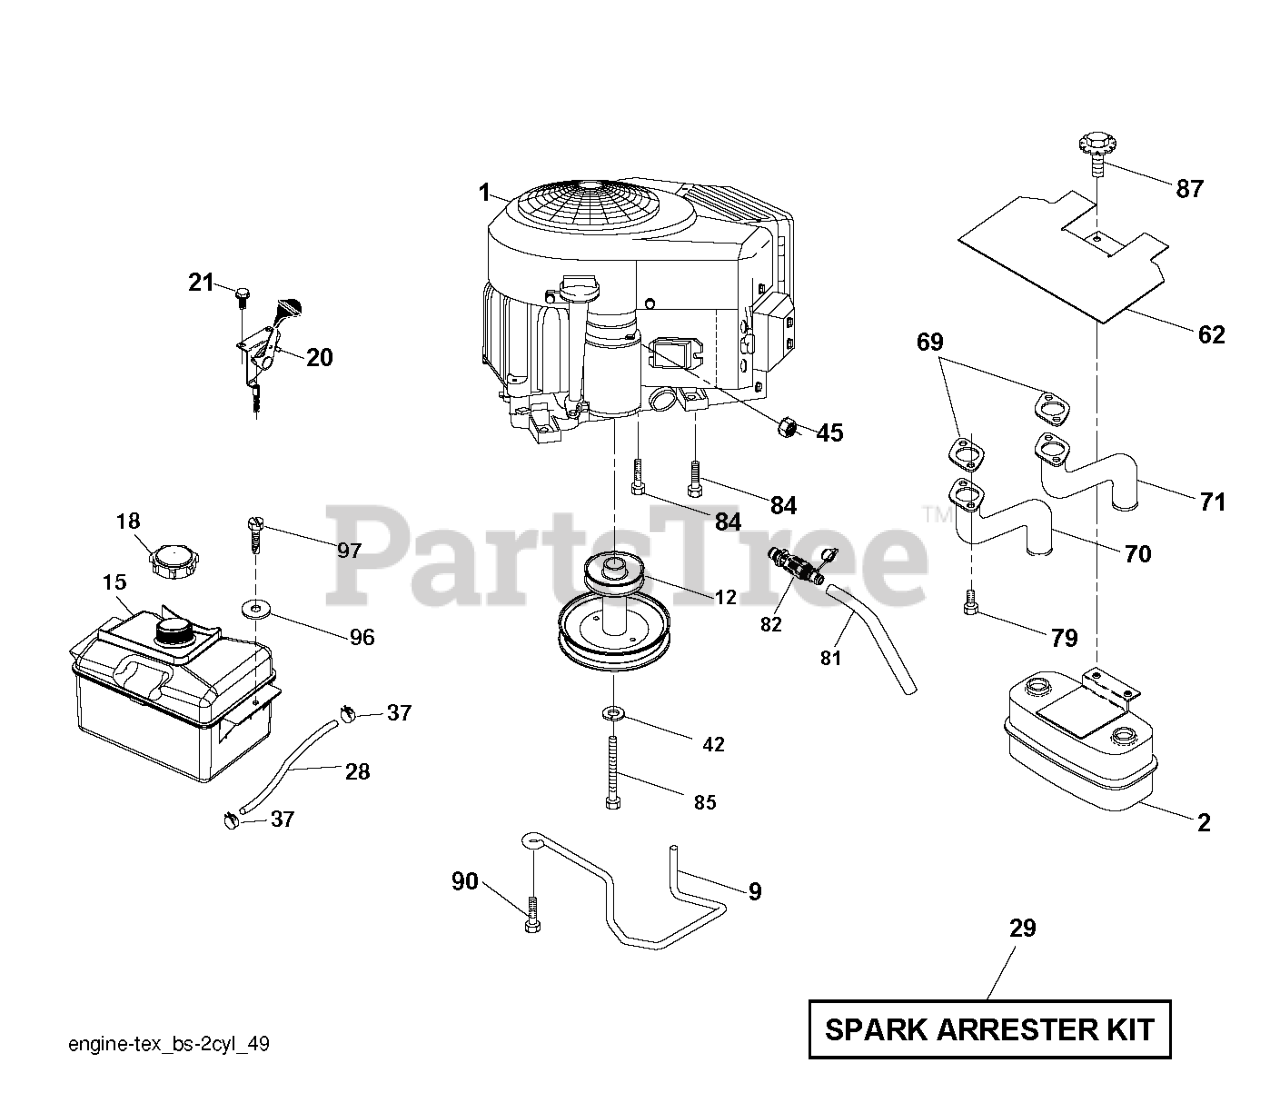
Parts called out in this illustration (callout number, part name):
2	MUFFLER.TWIN.CYL.LOW.TONE
9	KEEPER.BELT.ENGINE.4.2
12	RP_PULLEY ENGINE
15	TANK.ASM.FUEL.FR.2.5GA.
18	CAP ASM.FUEL.2.25"FR.
20	CONTROL.TH/CK.COBRA.B&S.TWN.BK
21	SCREW.#10 X 0.750.BOS
28	LINE.FUEL.20"FRONT.EMI
29	KIT.SPARK ARRESTOR 794945 B&S
37	HOSE CLAMP
42	LOCKWASHER
45	NUT
62	SHIELD.HEAT.MUFFLER
69	GASKET.MUFFLER
70	RP.EXHAUST.TUBE.LH.BS/TWIN
71	EXHAUST.TUBE.RH.BS/TWIN
79	SCREW.SOCKET.HEAD.5/16-18
81	TUBE, DRAIN OIL ASM.
82	VALUE.OIL.DRAIN
84	SCREW.3/8-16
85	BOLT HEX 7/16-20X4-1/4"
87	BOLT.5/16-18UNCX3/4 W/SEMS.BLK
90	SCREW 3/8-16X1
97	SCREW HEXWSHR 1/4-20X3/4
